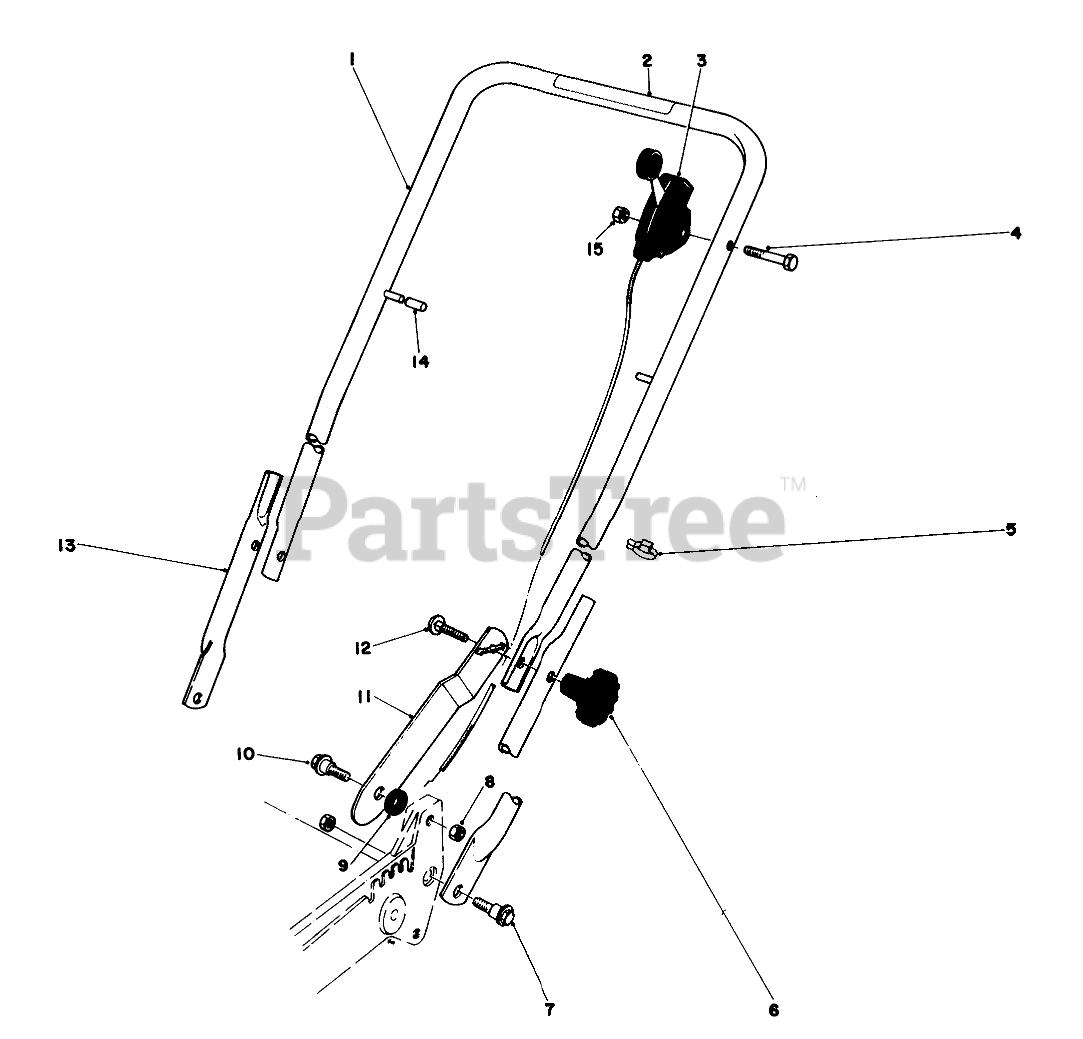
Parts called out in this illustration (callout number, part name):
1	Upper Handle
2	Decal
3	Throttle Control
4	SCREW-HH
5	BOWDEN CLIP
7	SCREW-SHOULDER
8	Nut
9	SPACER
10	Screw
11	Handle Latch L.H.
12	SCREW-CARR
13	LOWER HANDLE
14	CAP-VINYL
15	NUT-LOCK
